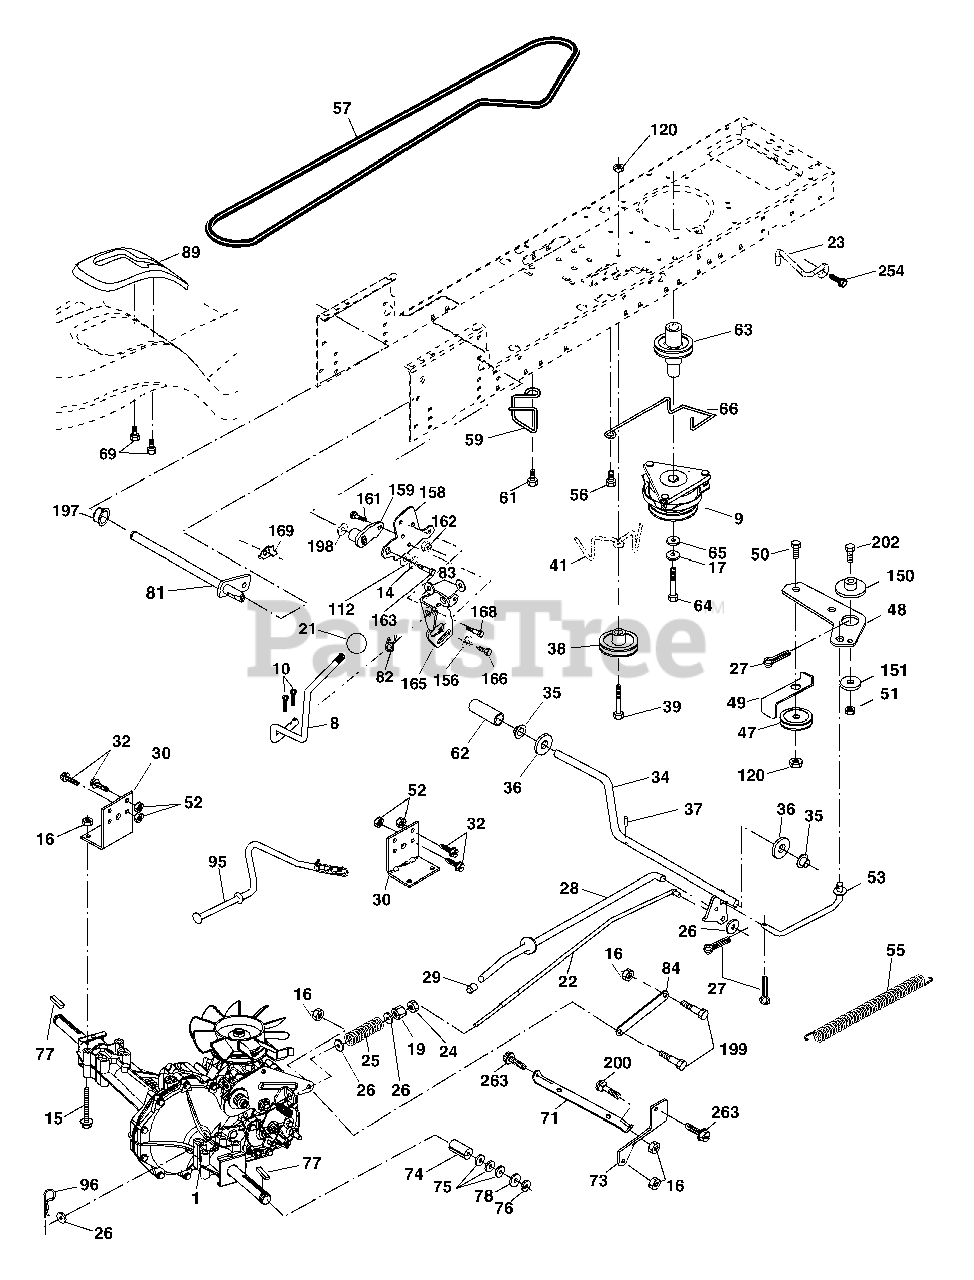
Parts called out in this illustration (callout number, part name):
8	Rod Shift Fend.
9	Clutch Electric
10	Pin Cotter 1/8 x 1
14	Washer Lock Hvy 1/4
15	Bolt Hex Flghd 5/16-18 Gr. 5
16	Nut Lock Hex W/Ins. 5/16-18 unc
17	Washer 1-1/2 x 15/32 x .250
19	Nut Lock Hex W/Wsh 3/8-16 unc
21	Knob
22	Rod, Brake
23	Bracket Asm Anti-Rotation
24	Nut, Hex Jam 3/8-16 unc
25	Spring, Brake Rod
26	Washer
27	Pin Cotter 1/8 x 3/4 CAD.
28	Rod, Parking Brake
29	Knob Brake Parking
30	Bracket, Transaxle
32	Bolt Hex Hd 5/16-18 unc x 3/4
34	Shaft, Foot Pedal
35	Bearing, Nylon
36	Washer
37	Pin, Roll
38	Pulley, Composite
39	Bolt Rdhd 3/8-16 unc x 2-3/4 Gr. 5
41	Keeper, Belt Idler Flat
47	Pulley, Idler, V-Groove
48	Bellcrank Clutch Grnd Drw Stl
49	Retainer, Belt
50	Bolt
51	Nut Crownlock 3/8-16 unc
52	Nut, Crownlock 5/16-18 unc
53	Link, Clutch
55	Spring, Return, Clutch
56	Screw 3/8-16 x 1-1/4
57	V-Belt, Ground Drive
59	Keeper, Center Span
61	Screw 3/8-16 x .875
62	Cover, Pedal
63	Pulley, Engine
64	Bolt, Hex 7/16-20 x 4 Gr. 5-1.5 Thr
65	Washer
66	Keeper Belt Engine
69	Screw Hex Wsh H-Lo 1/4-1/2 unc
71	Strap Torque LH
73	Strap Torque RH
74	Spacer, Axle
75	Washer 25/32 x 1-1/4 x 16 Ga.
76	E-Ring
77	Key, Square
78	Washer 25/32 x 1-5/8 x 16 Ga.
81	Shaft Assy. Cross Taper
82	Spring Torsion
83	Washer 17/32 x 3/4 x 16 Ga.
84	Link Transaxle
89	Console, Shift
95	Rod Bypass
96	Retainer Spring 1" Zinc/Cad
112	Washer 9/32 x 3/4 x 10 Ga.
120	Nut Lock Flg 3/8-16 unc
144	Washer 11/32 x 5/8 x 16 Ga.
150	Spacer Retainer
151	Washer 13/32 x 2 x 10 Ga.
156	Washer 5/16 ID x 1.0 x .125
158	Bracket Shift Mount
159	Hub Shift
161	Bolt Rdhd Sqnk 1/4-20 x 3/4 Gr. 5
162	Nut Crownlock 1/4-20 unc
163	Bolt Hex Fin 1/4-20 unc x 1 Gr. 5
165	Bracket Pivot Lever
166	Screw 5/16-18 x 5/8
168	Bolt Shoulder 5/16-18 x .561
169	Plate Fastener Cross Shf.
197	Nyliner Snap-in 5/8 ID
198	Washer Nyl 7/8 ID x .105"
199	Bolt Shoulder 5/16-18 unc
200	Bolt Rdhd Sqnk 5/16-18 unc x 1
202	Bolt Carr Sh 3/8-16 x 1-3/4 Gr. 5
254	Screw 3/8-16 x 1
263	Screw 3/8-16 x .75
